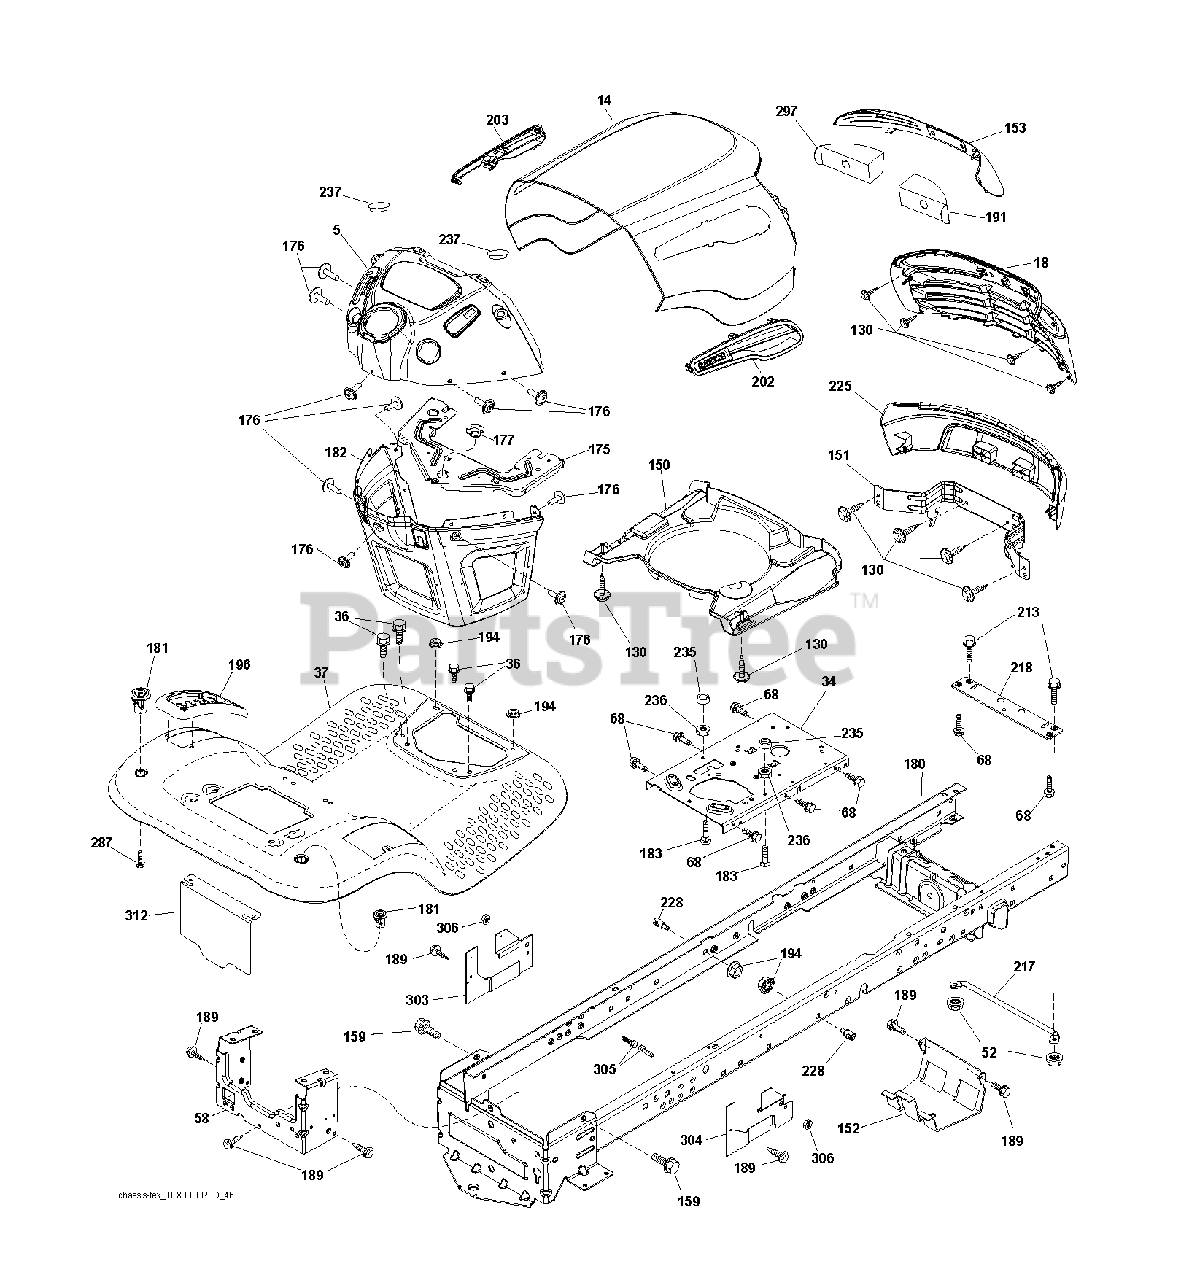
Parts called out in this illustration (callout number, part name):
34	PLATE.ENGINE.WELDED.CHASSIS
36	SCREW 5/16"
52	LOCKNUT
58	DRAWBAR UPPER 2PC SMALL FENDER
130	SCREW.#10 X 0.750.BOS THREAD
151	BRACKET.PIVOT.ALPHA.LT
152	SHIELD BROWNING
159	SCREW, 3/8-16X3/4
175	CROSSMEMBER
176	SCREW.#10-24X5/8.RN.QU
177	BUSHING STEERING
180	CHASS.WLDMNT.TL.12GA/2P.48/54
181	FEND/FTRST.PCH.CPH.NFW
182	DASH.LWER.PREDATOR/HUSQ.LT
183	BOLT.5/16-18X1-1/4 FULL THD
189	SCREW
191	INSERT.REFLECT.PREDATOR.LT.RH
194	NUT LOCK HEX FLANGE 5/16-18
196	CONSOLE.ASM.DECKLFT.BL/RBT.TLT
213	BOLT
217	ROD.PIVOT.HOOD
218	X-PIECE.HOOD.STOP.NON/
228	STUD.FASTNER.W/ANTI-ROTATE
235	SPACER FENDER
236	NUT.CENTERLOCK.5/16-
237	PLUG.MOUNT.CARGO.BLK
297	REFLECTOR.INSERT.PRED.LH.LT
306	NUT LOCK FLG 3/8-16 UNC
